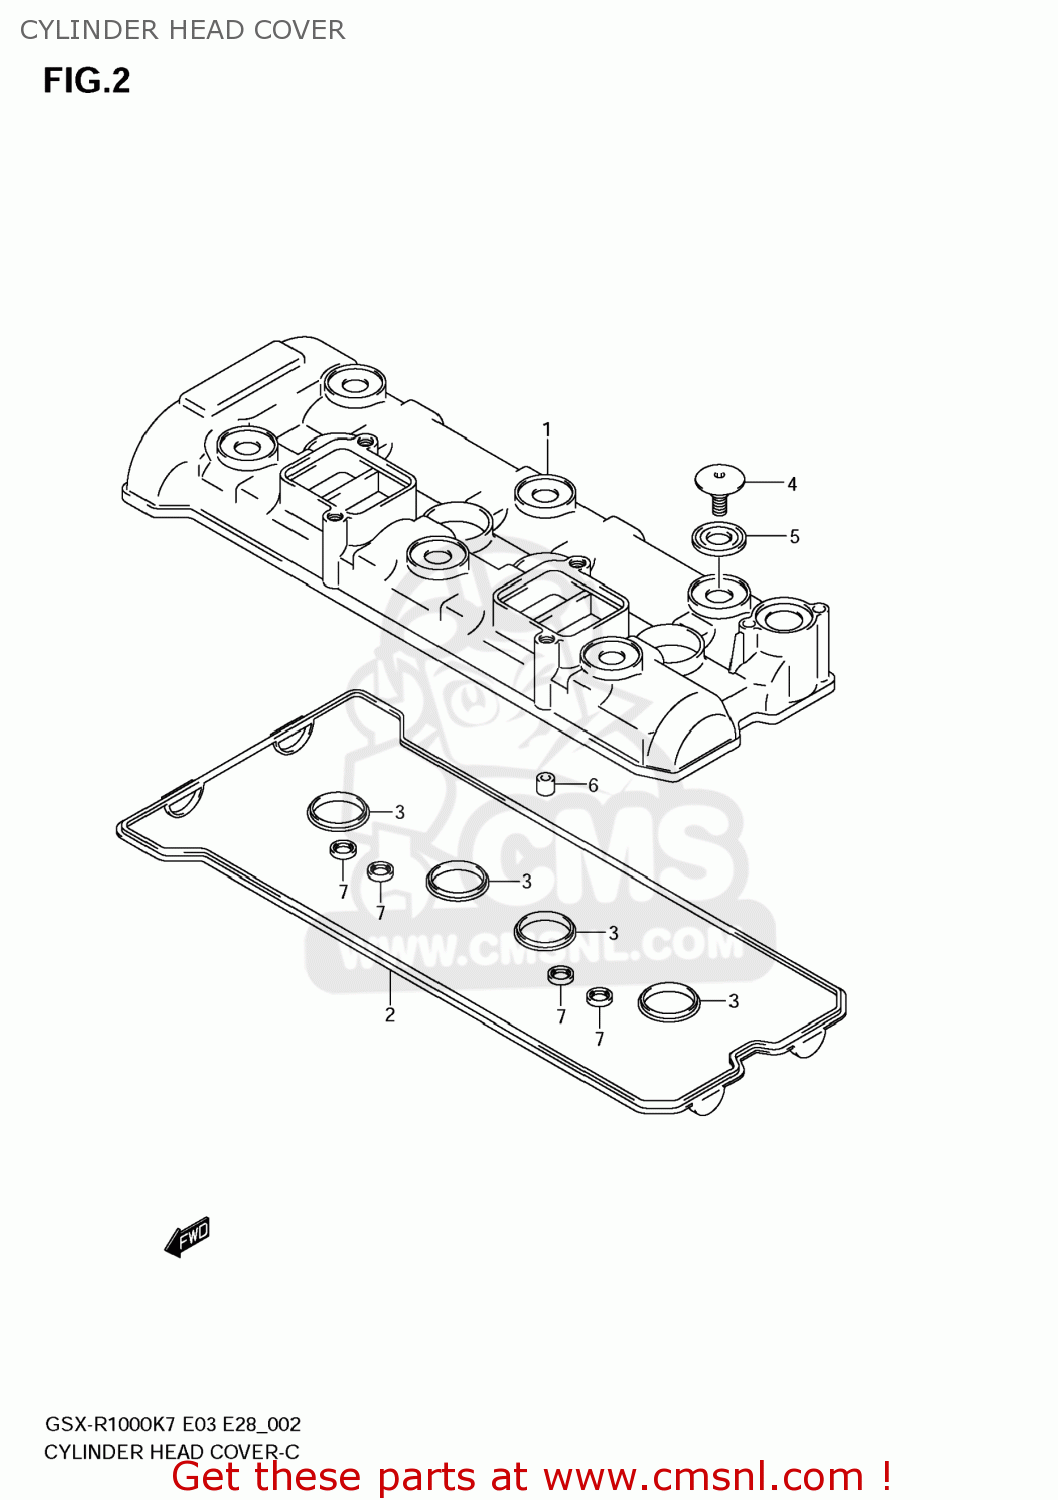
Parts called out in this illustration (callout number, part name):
1	COVER,CYLINDER HEAD
2	GASKET,CYL HEAD COVER NO.1 (NAS)
3	GASKET,CYL HEAD COVER NO.2
4	BOLT(7X17.5)
5	WASHER,CYL HEAD COVER
6	PIN(8.2X10X13)
7	GASKET,2ND AIR PASSAGE (NAS)
